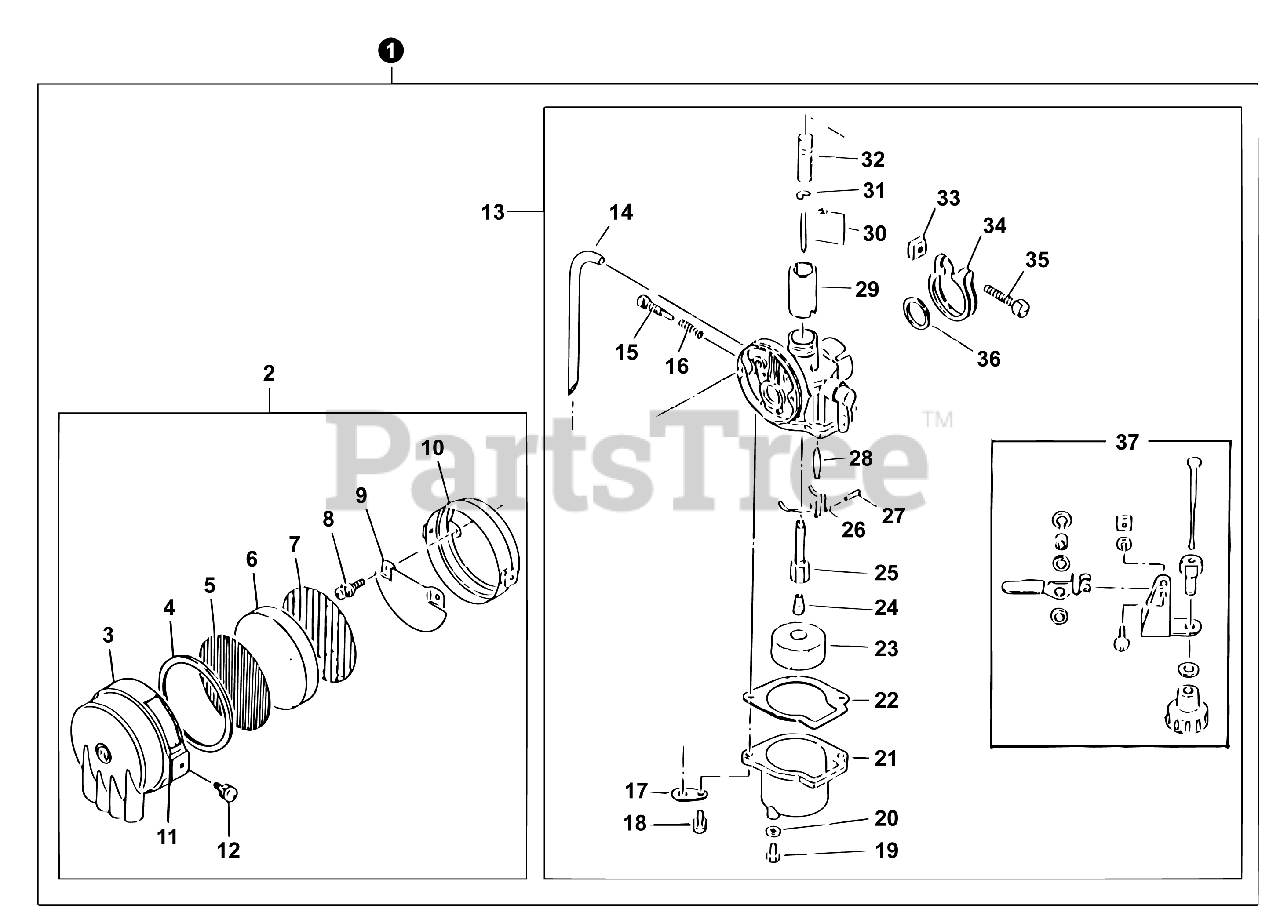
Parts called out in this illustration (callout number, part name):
1	CARBURETOR & AIR FILTER ASSY
2	FILTER ASSY, AIR
3	COVER, AIR FILTER
4	SEAL
5	SCREEN - FRONT
6	FILTER, AIR
7	SCREEN, REAR
8	SCREW
10	CASE, AIR FILTER
11	LABEL, CHOKE
12	SCREW 4
13	CARBURETOR
14	PIPE
15	SCREW, IDLE ADJUST
16	SPRING
17	HOLDER
18	SCREW
20	WASHER
21	CHAMBER, FLOAT
22	GASKET
23	FLOAT
24	JET, MAIN
25	NOZZLE
26	HINGE, FLOAT
27	PIN, HINGE
28	VALVE, INLET NEEDLE
29	VALVE, THROTTLE
30	NEEDLE, JET
31	WASHER
32	SPRING, THROTTLE
33	NUT
34	CLAMP
35	BOLT
36	GASKET, MOUNTING
37	THROTTLE CONTROL ASSY
